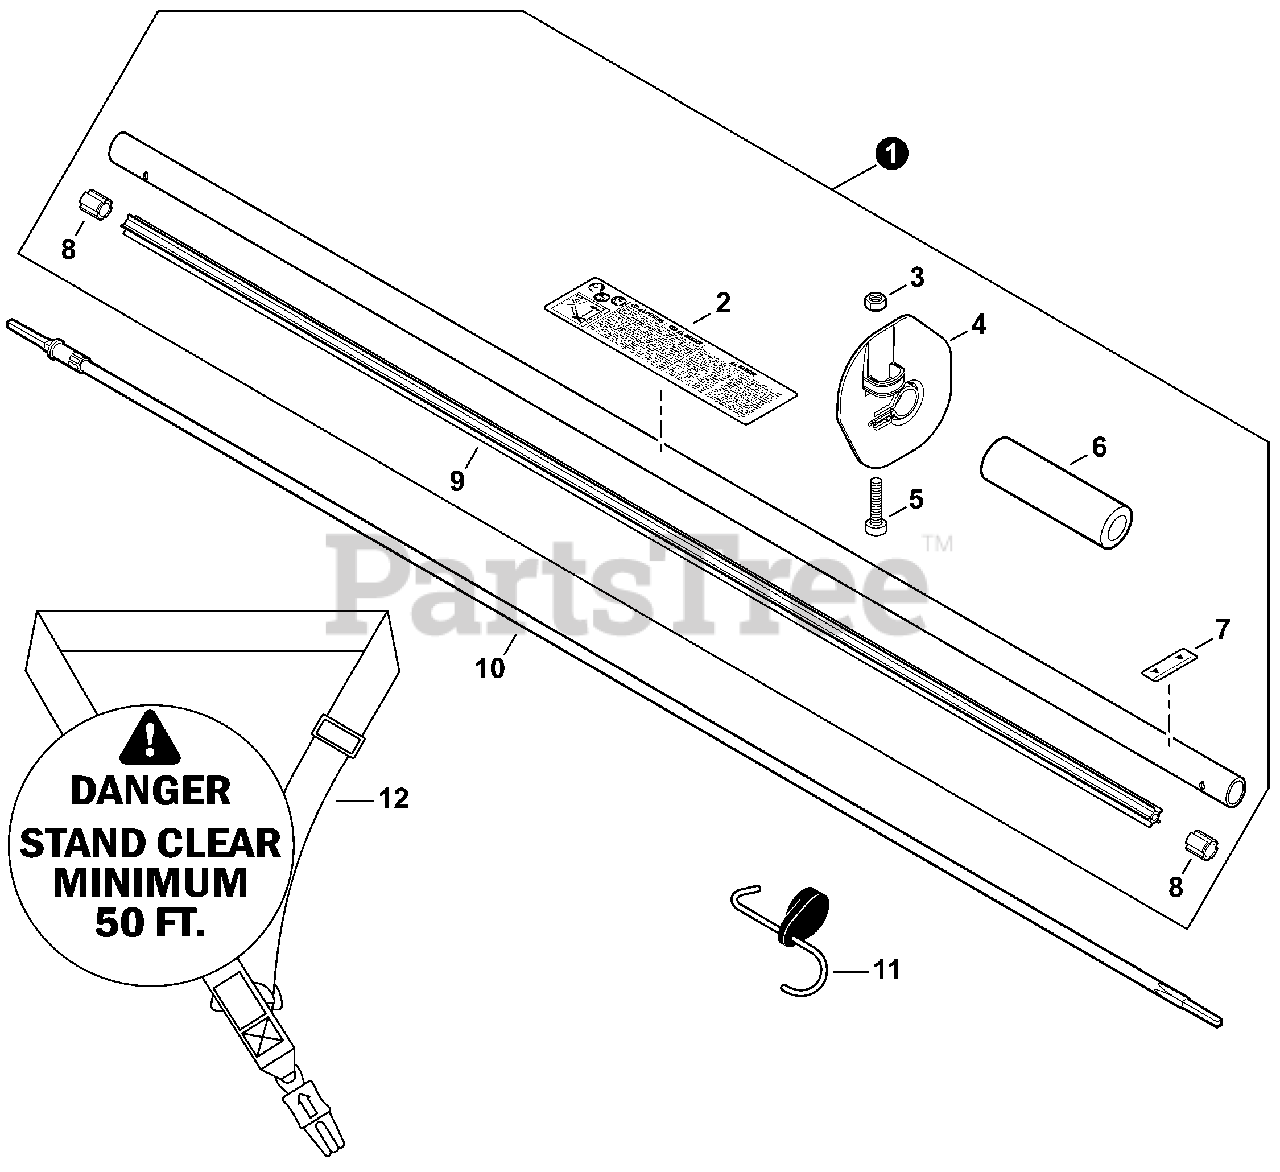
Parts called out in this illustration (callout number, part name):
1	MAIN PIPE ASSY
2	LABEL, CAUTION
4	GUARD, HAND
5	BOLT, TORX 5×20
6	GRIP, HANDLE
7	LABEL - ALIGNMENT
9	LINER - FLEXIBLE
10	DRIVESHAFT - FLEXIBLE
11	HANGER, ATTACHMENT
12	HARNESS, SHOULDER
